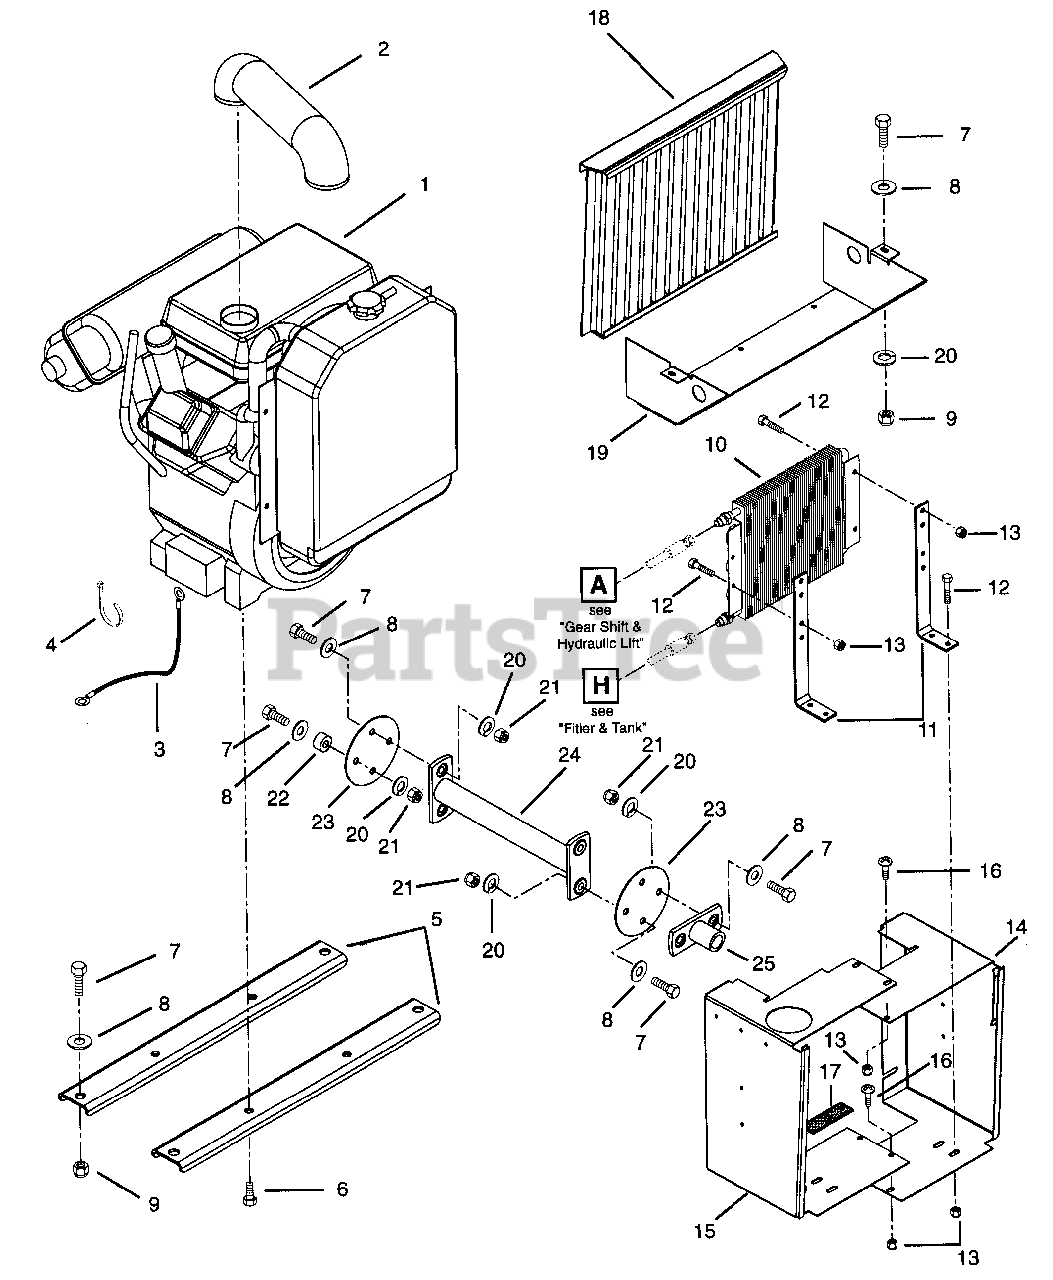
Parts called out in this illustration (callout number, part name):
1	Engine, 20 HP Kawasaki FD620D
2	Hose, Air Intake
3	Ground Strap
4	Tie Wrap, Black
5	Bracket, Engine Mount
6	Bolt-Hex M8 x 1.25 x 20MM
7	Bolt-Hex .375-16 x 1.00 Grade 5
8	Washer-Flat-Steel .38 x .875 x .083
9	Nut-Locking-Nylon .375-16 Grade 2
10	Cooler, Oil
11	Bracket, Oil Cooler Mount
12	Bolt-Hex .25-20 x 1.00 Grade 5
13	Nut-Lock-Nylon .250-20 Grade 2
14	Weldment, Intake Duct Left Hand
15	Weldment, Intake Duct Right Hand
16	Screw, 1/4-20 x .50
17	Seal, Trim-Lok Bulk
18	Grille, Radiator
19	Shield, Bottom Air Intake
20	Washer-Lock .375 x .094
21	Nut-Hex .375-16 Grade 2
22	Spacer .406 I.D. x .88 O.D. x .38 Long
23	Flex Coupling Disc
24	Weldment, Transmission Drive
25	Weldment, Transmission Coupling
